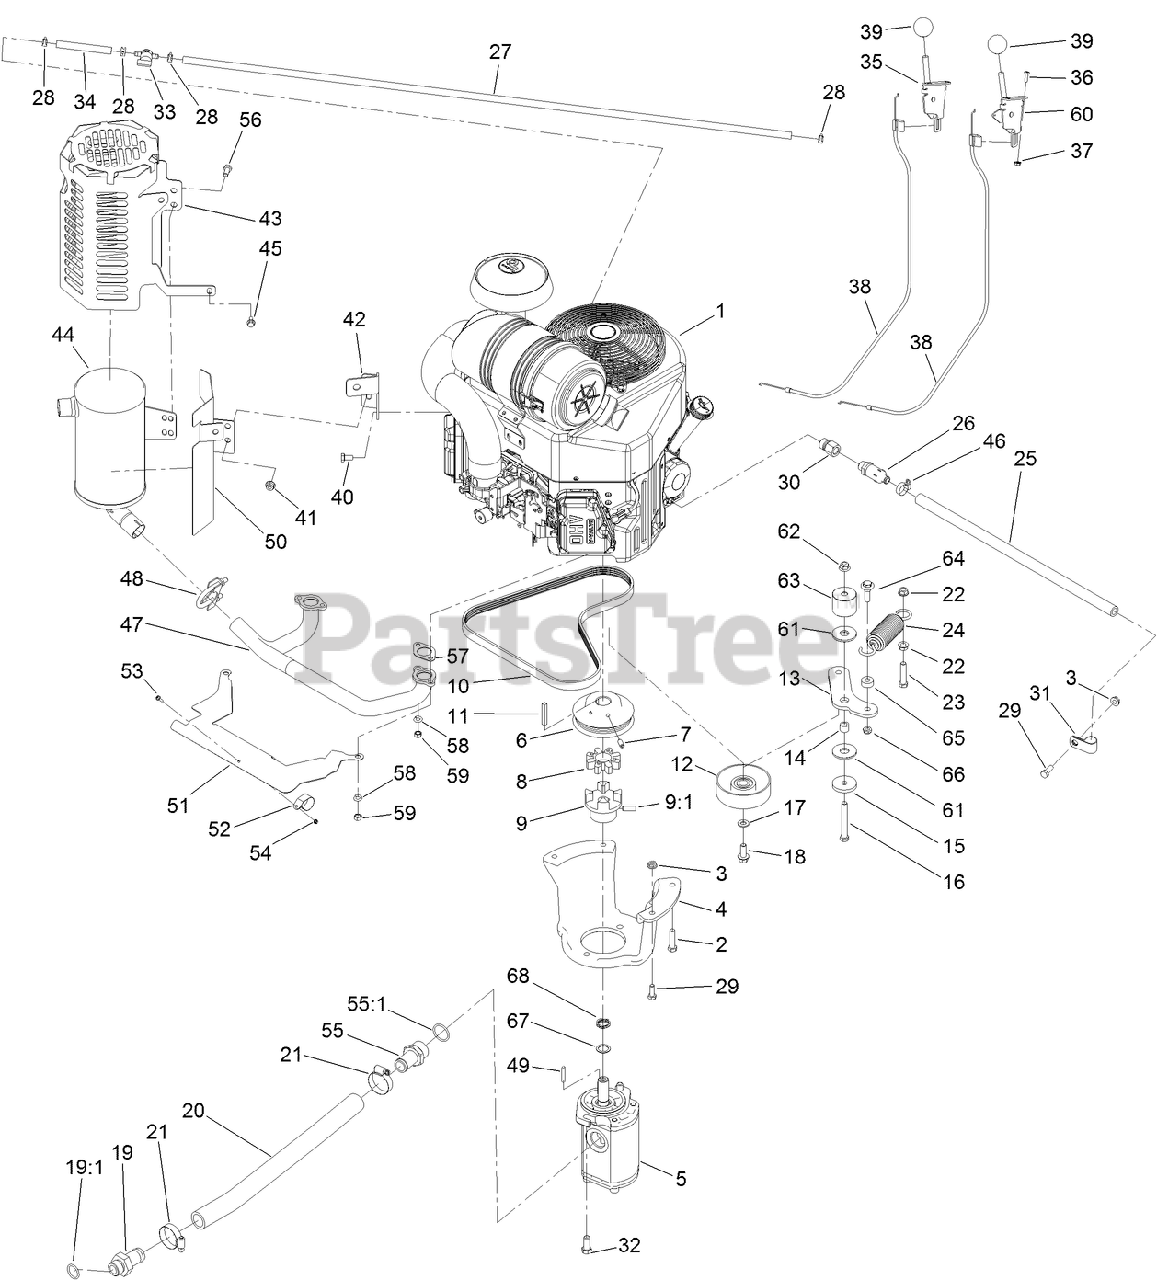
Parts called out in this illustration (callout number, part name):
1	ENGINE-KAWASAKI, FX730V
2	SCREW-HH
3	NUT-HF
4	MOUNT-PUMP
5	GEAR PUMP ASM
6	PULLEY-ENGINE
7	SCREW-SET, HSH
8	COUPLER-SPIDER
9	COUPLER-FLEX
9:1	SCREW-SET
10	BELT-V
11	KEY-SQUARE
12	PULLEY-IDLER
13	ARM-IDLER
14	BUSHING-LEVER, LIFT
15	WASHER-PLAIN
16	SCREW-HH
17	WASHER-FLAT
18	SCREW-HHF
19	FITTING
19:1	O-RING
20	HOSE-SUCTION
22	NUT-HHF, WHIZ
23	SCREW-HH
24	SPRING-EXTENSION
25	HOSE-VENT
26	VALVE-DRAIN, OIL
27	HOSE-FUEL
28	CLAMP-HOSE
29	SCREW-HH
30	Adapter
31	CLAMP-R
32	SCREW-HH
33	VALVE-FUEL
34	HOSE-FUEL
35	LEVER-CONTROL
37	NUT-LOCK, FLANGE
38	CABLE-CONTROL
40	SCREW-HH
41	NUT-HF
42	BRACKET-MOUNT, MUFFLER
43	SHIELD-MUFFLER
44	MUFFLER
45	SCREW-HHF
46	CLAMP-HOSE
47	MANIFOLD
48	CLAMP-MUFFLER
49	KEY-SQUARE
50	BRACKET-SHIELD, HEAT
51	PLATE-SHIELD, HEAT
53	SCREW-PAN
54	NUT-HEX
55	FITTING-STR
55:1	O-RING
56	SCREW-HH
57	GASKET-EXHAUST
58	WASHER-SPRING
59	NUT-HEX
60	LEVER-CONTROL
61	WASHER-FRICTION, COMPOSITE
62	NUT-HF, NI
63	SPACER-IDLER
64	SCREW-SHOULDER, HWH
65	SPACER
66	NUT-LOCK, NI
67	WASHER-THRUST
68	WASHER-WAVE
